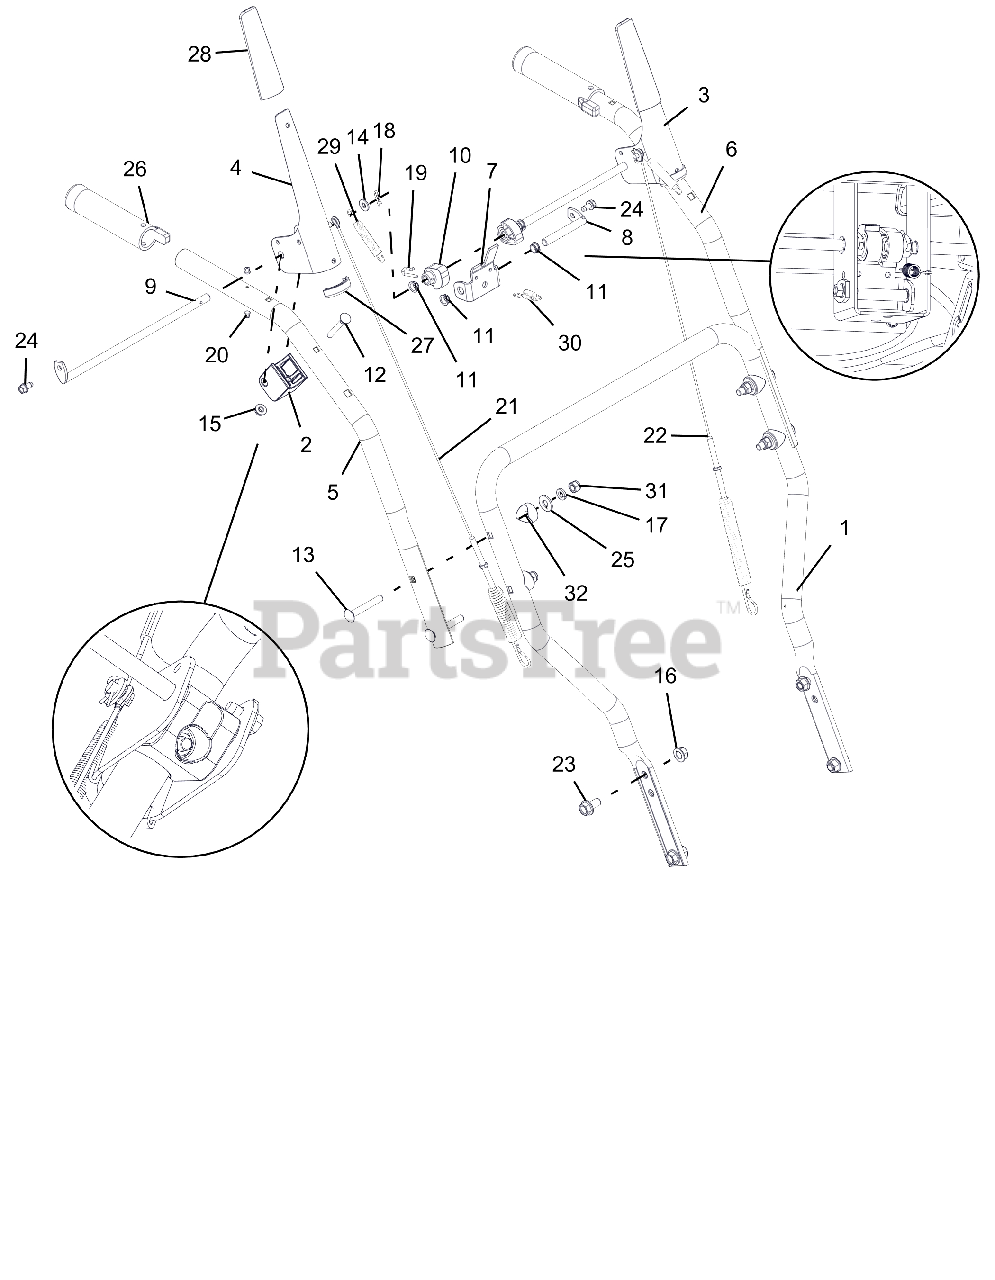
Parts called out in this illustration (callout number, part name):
1	HANDLEBAR, LOWER
2	BLOCK, CLUTCH PADDLE
3	LEVER, CLUTCH-LH
4	LEVER, CLUTCH-RH
5	HANDLEBAR, UPPER - RH
6	HANDLEBAR, UPPER - LH
7	BRACKET, INTERLOCK ARM
8	ROD, PIVOT - INTERLOCK
9	ROD, PADDLE MOUNT - PRO
10	CAM, INTERLOCK
11	BUSHING, POLYLINER-.38 SNAPIN
12	BLT-RDHDXLSQNK .25-20X2.0 G5YZ
13	@BLT-RDHDSQNK .31-18X2.25 G5YZ
14	@WSHR-FL-STL.281X.62X.065 YWZC
15	@NUT-LK-CTR-FLG .25-20 YWZC
16	@NUT-LK-TOP-FLG .38-16 YWZC
17	WSHR-LK .312X.097 HVY YWZC
18	PIN-HAIR INT .06X.18X.77
19	PIN, SPRING CLIP
20	RVT-POP #43 .125X.313 STL ZINC
21	CABLE, AUGER (DELUXE & PRO)
22	CABLE, UPPER TRACTION
23	BLT-SERHFWH .38-16X.75 YWZC
24	SCR-TAP .25-20X.50 HWH TR YWZ
25	@WSHR-FL-STL.38X.875X.083 YWZC
26	HEATED GRIP, MAGURA
27	EDGING, CLUTCH PADDLE - 2.00"
28	CLUTCH PADDLE SLEEVE - GRAY
29	SPRING, EXTENSION
30	SPRING-EXT .047X.438X1.45
31	@NUT-LK-NYL .312-18 YWZC
32	SPACER, HANDLEBAR
